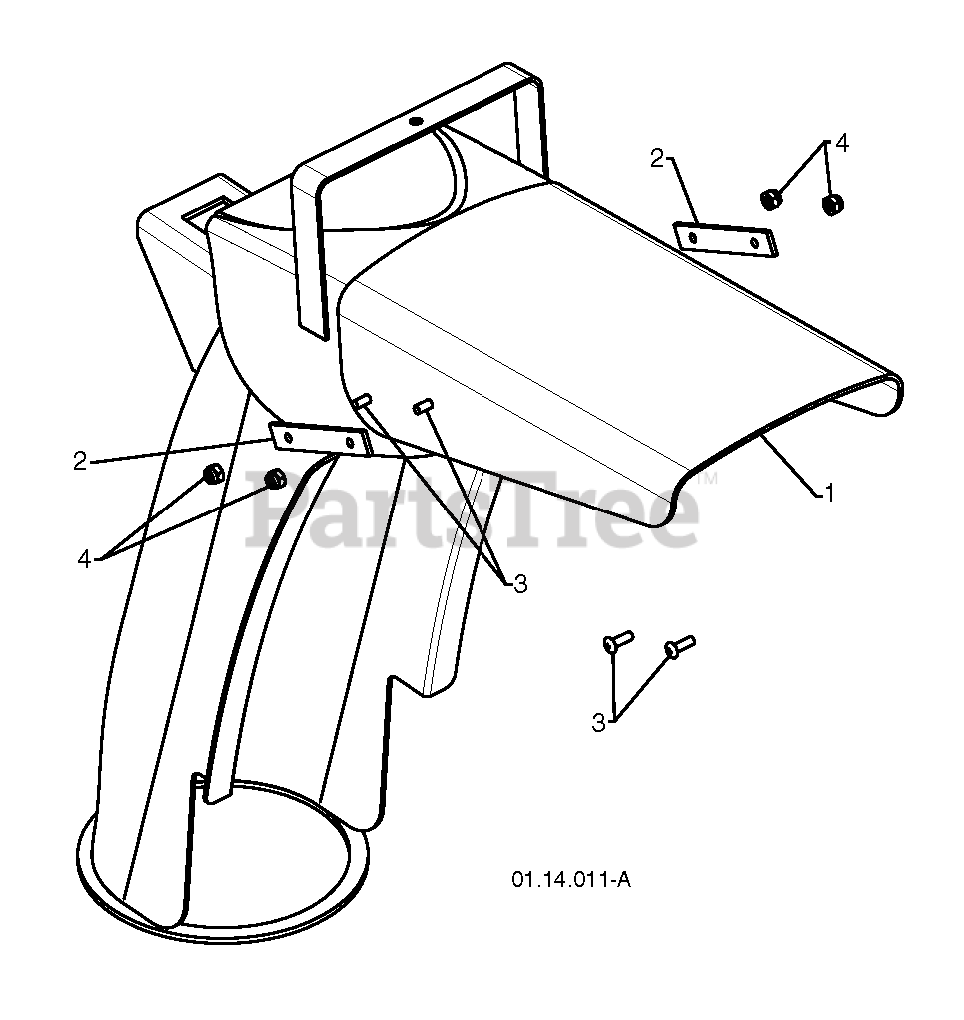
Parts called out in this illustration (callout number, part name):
1	SHIELD.DEFLECTOR.BLACK.SNOW
2	STRAP.DEFLECTOR.SHEILD
3	SCREW.#8.MACH
4	NUT.HEX.#8
